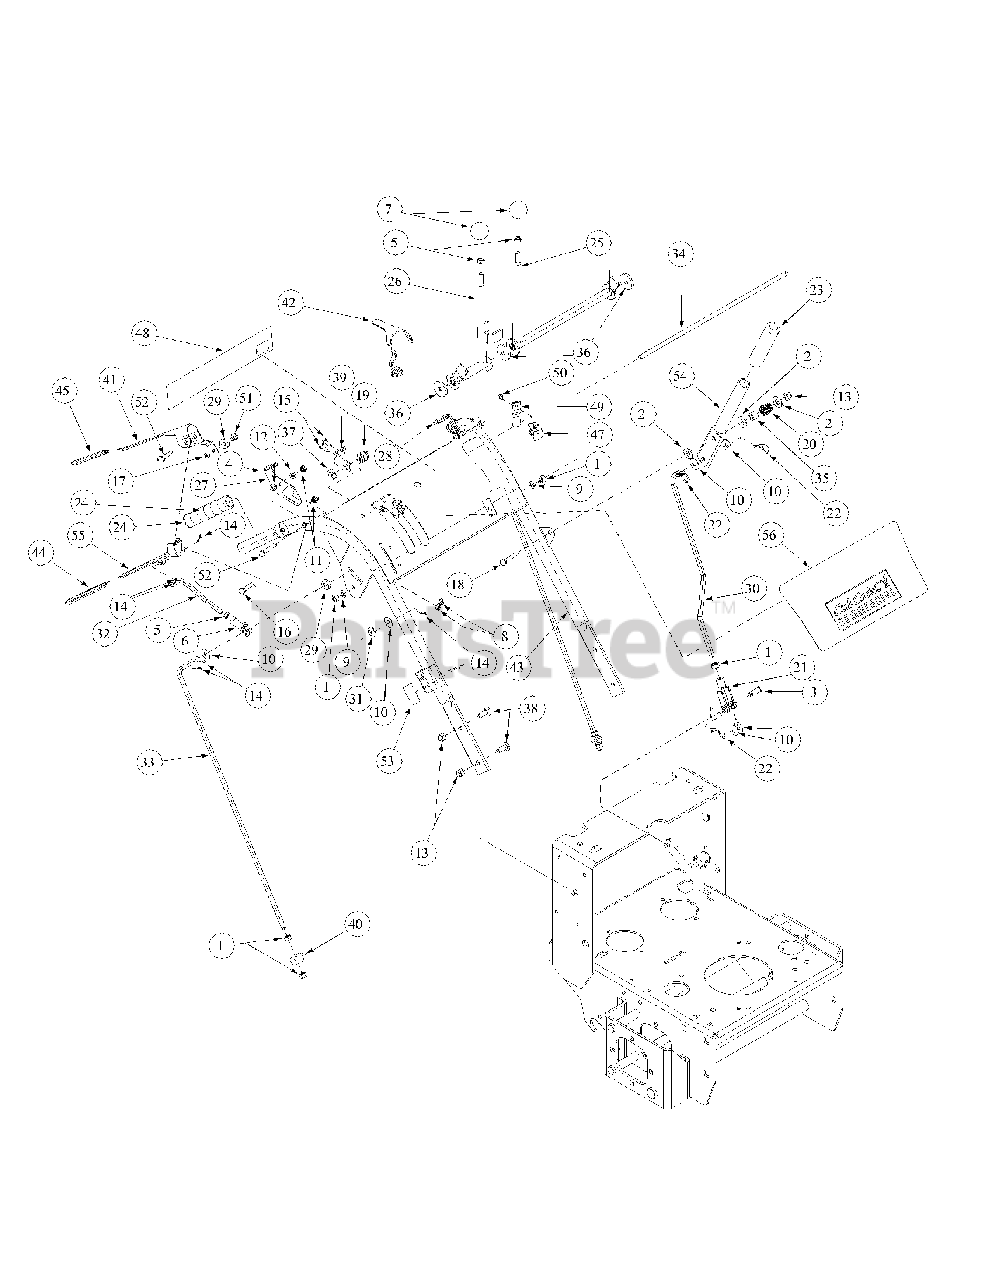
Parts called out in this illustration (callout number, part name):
1	Hex Nut, 3/8 - 16
2	Flat Washer, SS, 3/8
3	Clevis Pin, 3/8 x 1 1/8
4	Grip, 1.25, Black Neutral Lock
5	Hex Nut, Jam, 3/8-24
6	End Rod, 3/8
7	Knob, 1-3/8 x 1-19/64, 3/8-24
8	Lock Nut, Nylon Insert, 1/4-20
9	Lock Washer, 3/8 Zinc
10	Flat Washer, 3/8, SAE
11	Nut, 5/16-18
12	Flat Washer, SAE 5/16
13	Lock Nut, Nylon Insert, 3/8-16
14	Cotter Pin, 5/32 x 1-1/2 Zinc
15	HHCS, 1/4-20, .75
16	HHCS, Standard, 5/16-18 x 2
17	Lock Nut, Nylon Insert, 1/4 - 28
18	Carriage Bolt, 3/8 -16 x 2
19	Switch Operator's Presence
20	Spring, .850
21	Yoke, 3/8 - 16, Female
22	Hair Pin, 3/8 - 1/2
23	1" Grip, Black Handle
24	4-5/8" Grip, Black Plastic Handle
25	Control Assembly, Speed Hydro, LH
26	Control Assembly, Speed Hydro, RH
27	Latch, RH, Neutral Hydro
28	Latch, LH, Neutral Hydro
29	Hydro, Spacer Control Rod
30	Blade Clutch, Hydro Rod Base
31	Hydro Bush Control Rod
32	Control Rod, Short Hydr
33	Control Rod, Long Hydr
34	Hydro Rod, Speed Control
35	Sleeve Spring, 32/36/4
36	Friction Washe
37	Hex Nut, Dead Man Switch
38	Carriage Bolt, 3/8 -16 x
39	Mounting Switch, Neutral, Safet
40	Pivot, Belt Tightene
41	Operator Presence Control Handle, R
42	Operator Presence Control Handle, L
43	Hydro, Handle Assembl
44	Control Sleeve, Drive Black
45	Operators Control Sleeve,Yellow
46	Harness Adapter Assembly
47	Snap Mounting Switc
48	Handle Label
49	Retension Spring
50	Screw, TT, 10-24,
51	Shoulder Screw, .38 x .412, 1/4-2
52	HHCS, 5/16-18, 2.00
53	Parking Brake Deca
54	Blade Clutch Lever
55	Lever Assembly Control
56	Label, Pane
